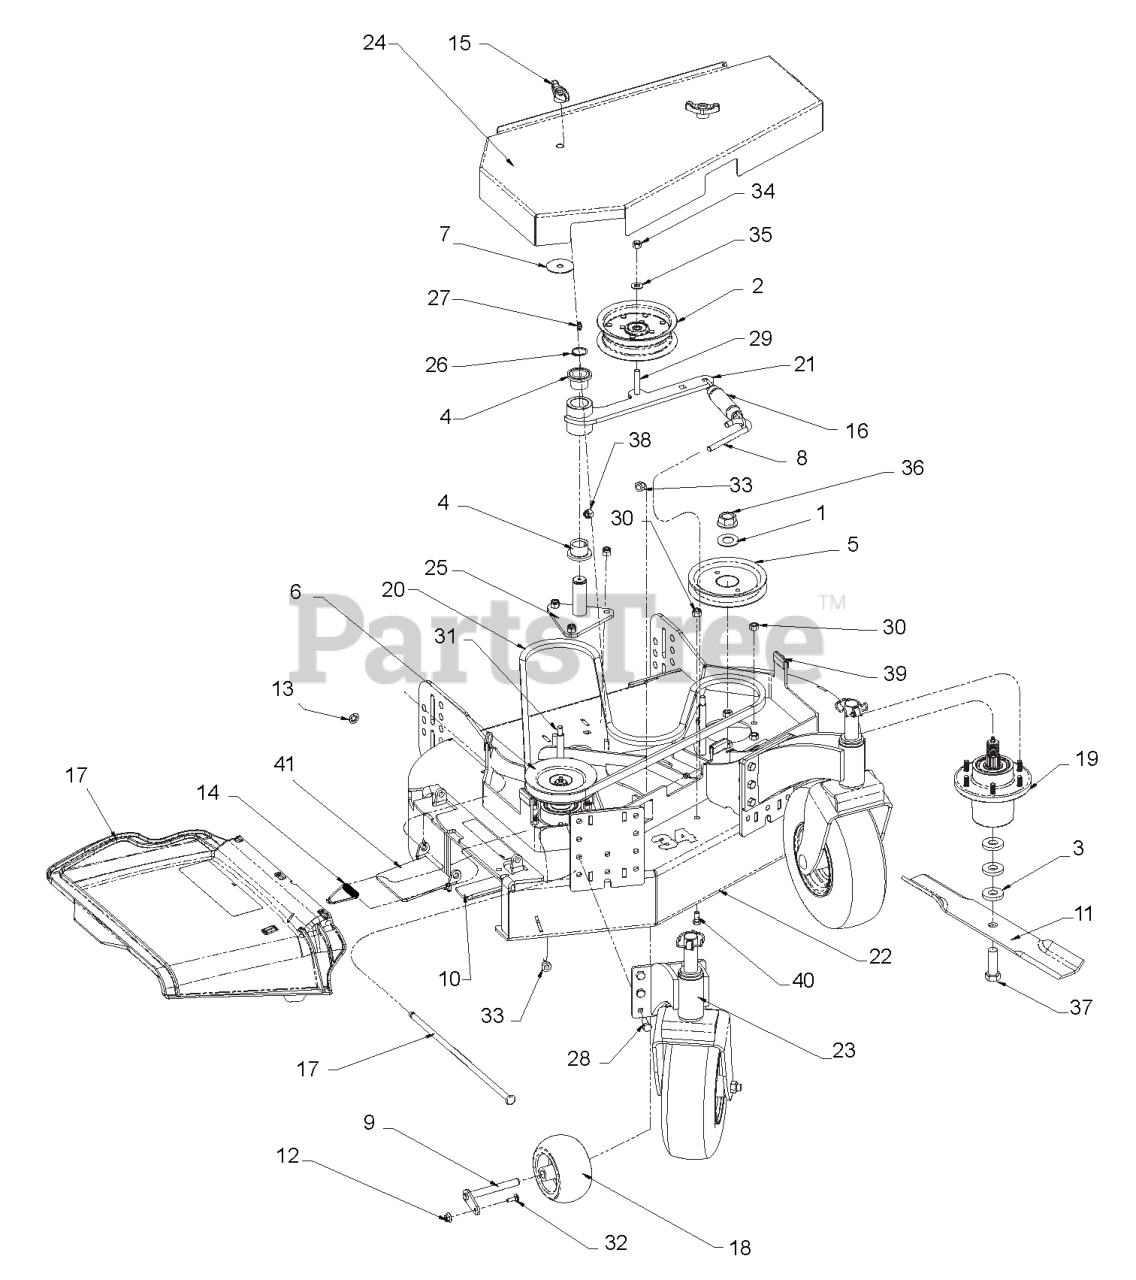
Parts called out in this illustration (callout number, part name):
1	WASHER, .75X1.3125X.120
2	PULLEY, FLAT 5.00X.375 W/BRG
3	WASHER, .630X1.50X.250 FLAT Y
4	BRG, FLG 1.00X1.25X1.00
5	PULLEY, SPLINE SPINDLE LSE
6	PULLEY, SPLINE SPINDLE LSE
7	WASHER, .402X2.00X.055 FEND Y
8	J-BOLT, 3/8-16 X 4.00 Y
9	PIVOT, RETAINER WELD
10	BLADE, 16.500 X .80 LIFT
11	BLADE, 18.000 X .80 LIFT
12	NUT-1/4" FLANGE PREVAILING TOR
13	RETAINER #
14	SPRING, TORSION .460"X.138"
15	KNOB, 3/8-16 INSERT
16	SPRING, EXT
17	CHUTE DISCHARGE ASSY #
18	WHEEL, GAGE
19	ASSY, SPINDLE HOUSING
20	BELT, HB 80.3 EL AMD OHR
21	WLDT, IDLER ARM
22	WLDT, FIXD DECK GRDNE W/DECALS
23	Assembly, Front Wheel Caster (see page 16 for parts)
24	SHIELD, DECK W/DECALS GRT DANE
25	WLDT, IDLER PIVOT
26	SNAP RING, 1.00 X .042 EXT
27	FTG, 1/4-28 STRGT GREASE ZERK
28	BOLT, 3/8-16X1.00 HEX 5 Y
29	BOLT, 3/8-16X2.25 HEX 5 Y
30	NUT, 3/8-16 STD HEX GR5 Y
31	BOLT, 3/8-16X1.00 CRG 5 SN Y
32	BOLT, 1/4-20X.750 CRG 5 Y
33	LOCKNUT, 3/8-16 WHIZ Y
34	LOCKNUT, 3/8-16 CROWN Y
35	WASHER, .406X.813X.065 FLAT Y
36	LOCKNUT, 3/4-16 CROWN PL
37	BOLT, 5/8-11 X 2.00 HEX 8 Y
38	LOCKNUT, 3/8-16 NYLOC Y
39	TRIM, LOCK 1/4" EDGE
40	BOLT, 3/8-16X.750 CRG 5 LN Y
41	BRKT, SUPPORT DISCHARGE CHUTE
